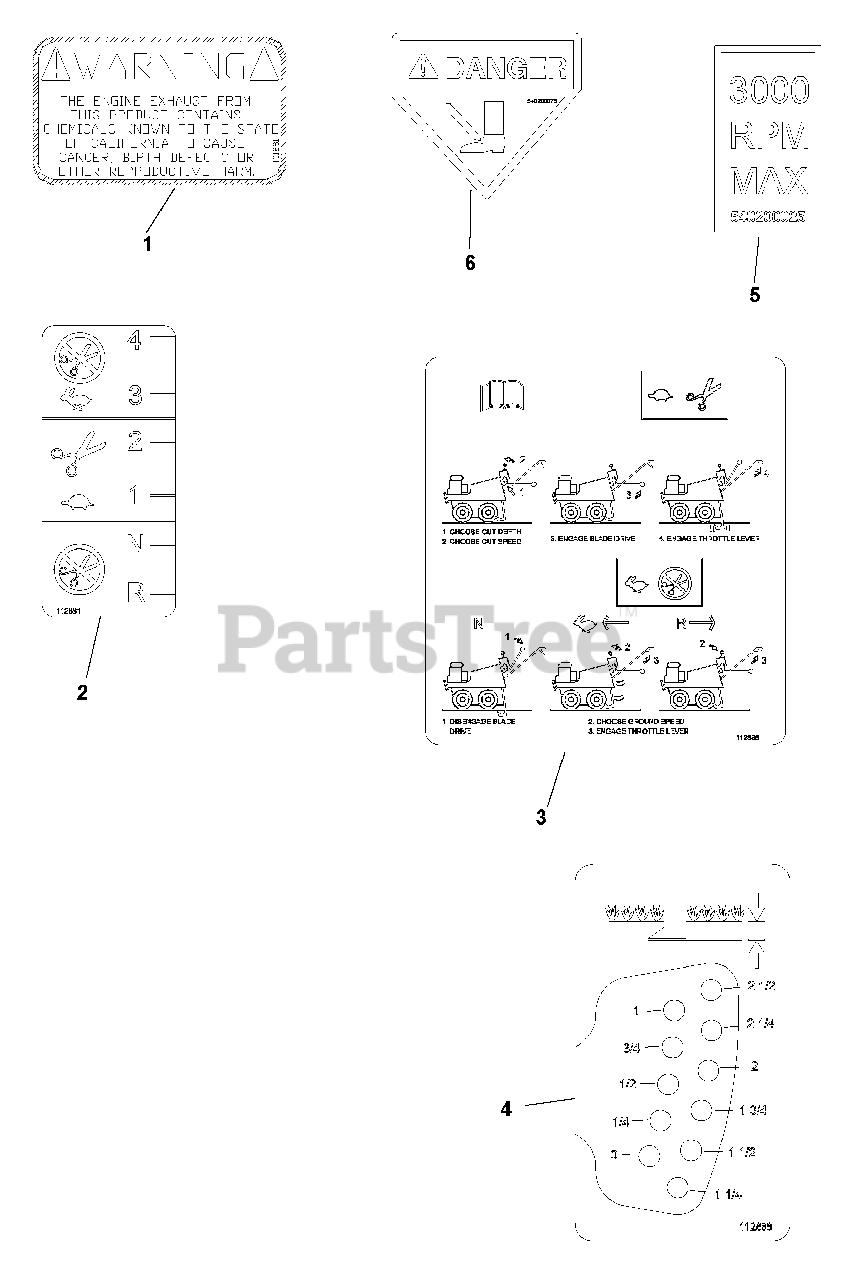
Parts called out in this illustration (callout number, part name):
1	DECAL, PROP 65
2	DECAL, SHIFT
3	DECAL, OPERATION
4	DECAL, DEPTH OF CUT
5	DECAL, 3000 MAX RPM
6	DECAL, DANGER FOOT
